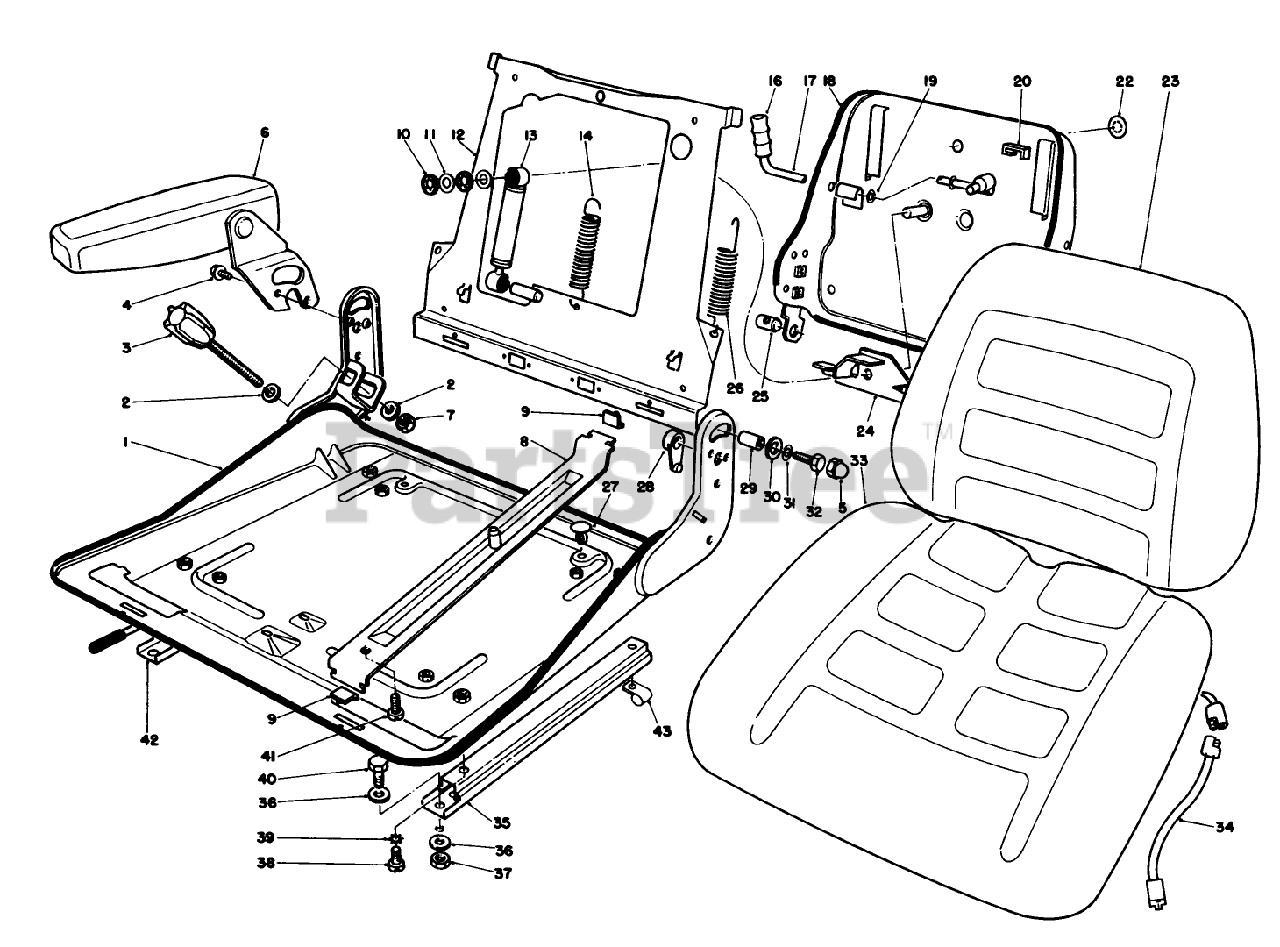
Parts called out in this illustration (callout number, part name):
1	Platform-Seat
2	WASHER
4	SCREW
5	COVER
6	RH ARMREST ASM
8	Carrier-Seat
10	CLAMP
11	Washer-Flat
12	Back Plate
13	SHOCK ABSORBER
14	SPRING
16	Cover-Grip
17	LEVER
18	Cover-Seat Back
19	WASHER
20	BUMPER
22	COVER
23	Cushion-Seat Back
24	LEVER
26	SPRING
28	SPACER
29	BUSHING
30	WASHER
31	WASHER
32	SCREW
33	CUSHION
34	JUMPER WIRE ASM
35	Bottom Rail Assembly L.H.
36	WASHER-PLAIN
37	NUT-LOCK, NI
38	SCREW
39	WASHER
40	SCREW-HH
41	SCREW
42	Bottom Rail Assy. R.H.
43	CLAMP
